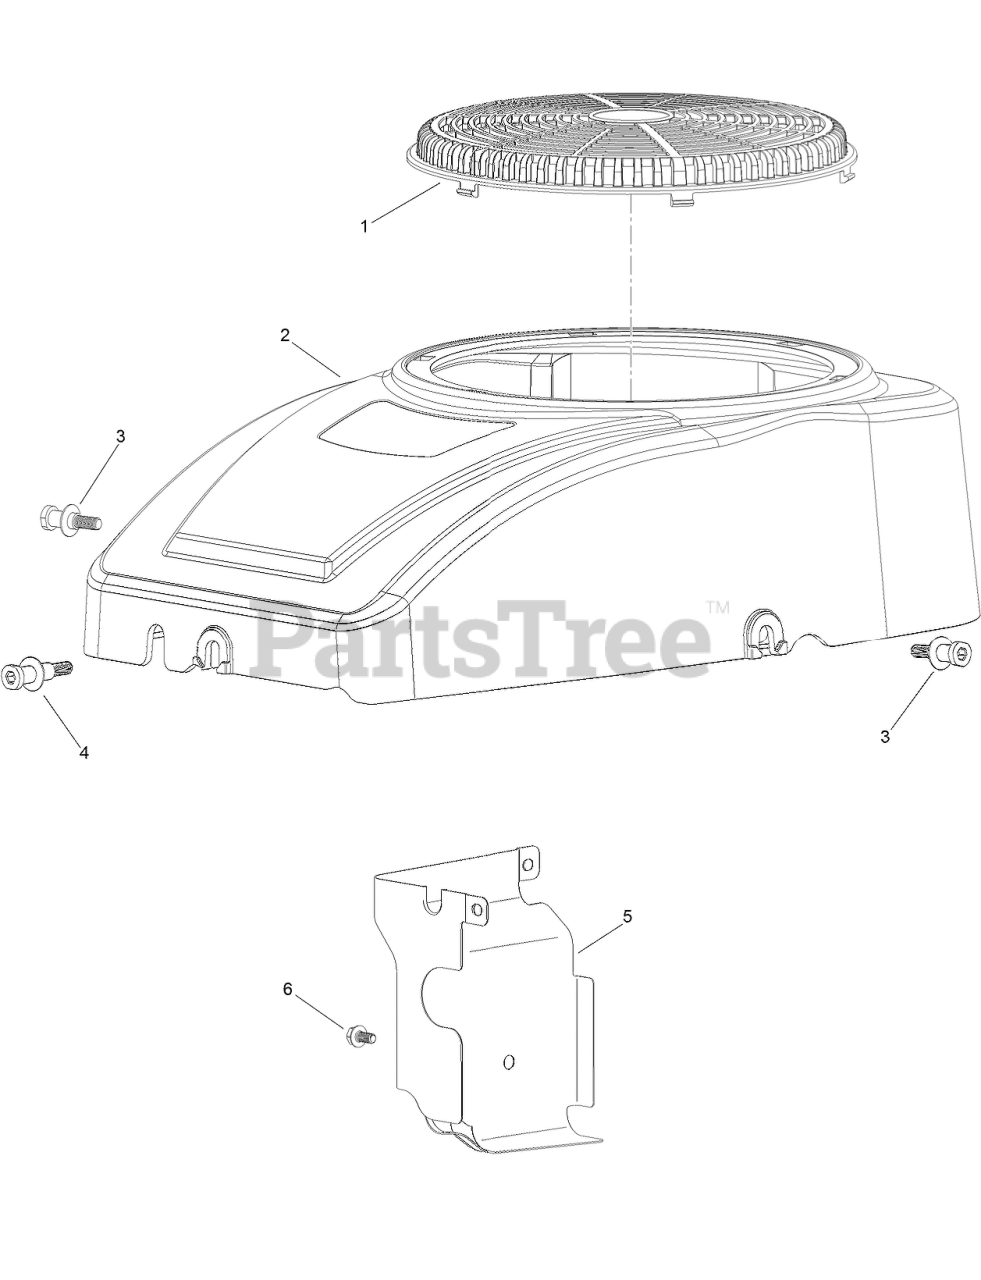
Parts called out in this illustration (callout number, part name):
1	SCREEN-STATIONARY
2	SHROUD-FAN
3	SCREW-SHOULDER, HH
4	SCREW-SHOULDER, HH
5	SHIELD
6	SCREW-HHF
